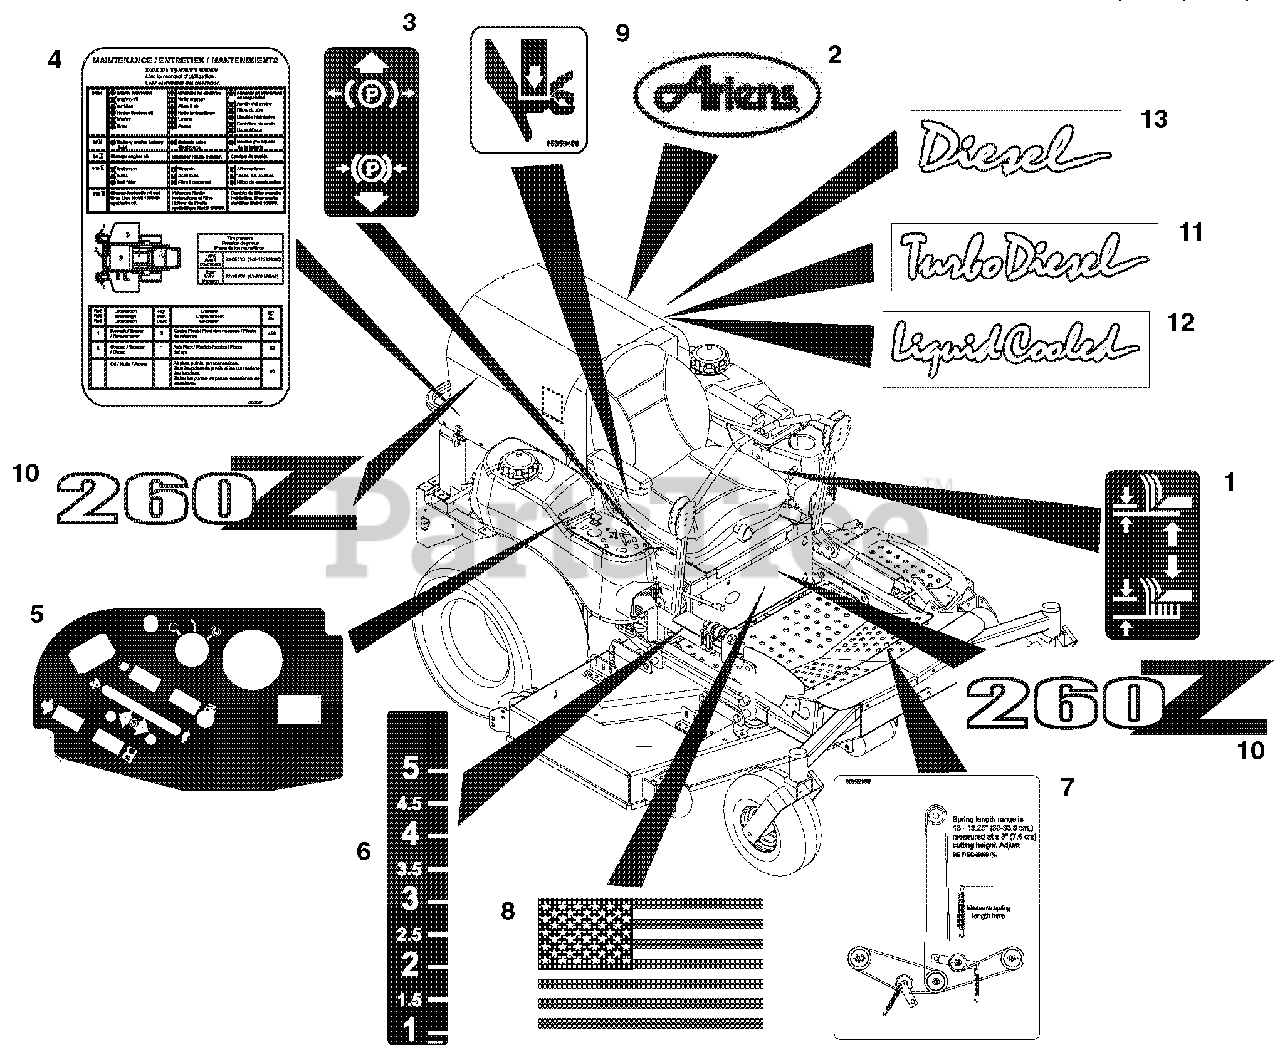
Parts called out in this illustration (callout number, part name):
1	DECAL- LIFT LEVER
2	DECAL, ARIENS
3	DECAL, PARKING BRAKE LEVER
4	DECAL-MAINTENANCE INSTRUCTIONS
5	DECAL - CONTROL PANEL - XDZ
6	DECAL, HEIGHT OF CUT
7	DECAL, BELT DIAGRAM
8	DECAL, AMERICAN FLAG
9	DECAL, PINCH POINT
10	DECAL, PM-260Z
11	DECAL, TURBO DIESEL
12	DECAL, LIQUID COOLED
13	DECAL, DIESEL
